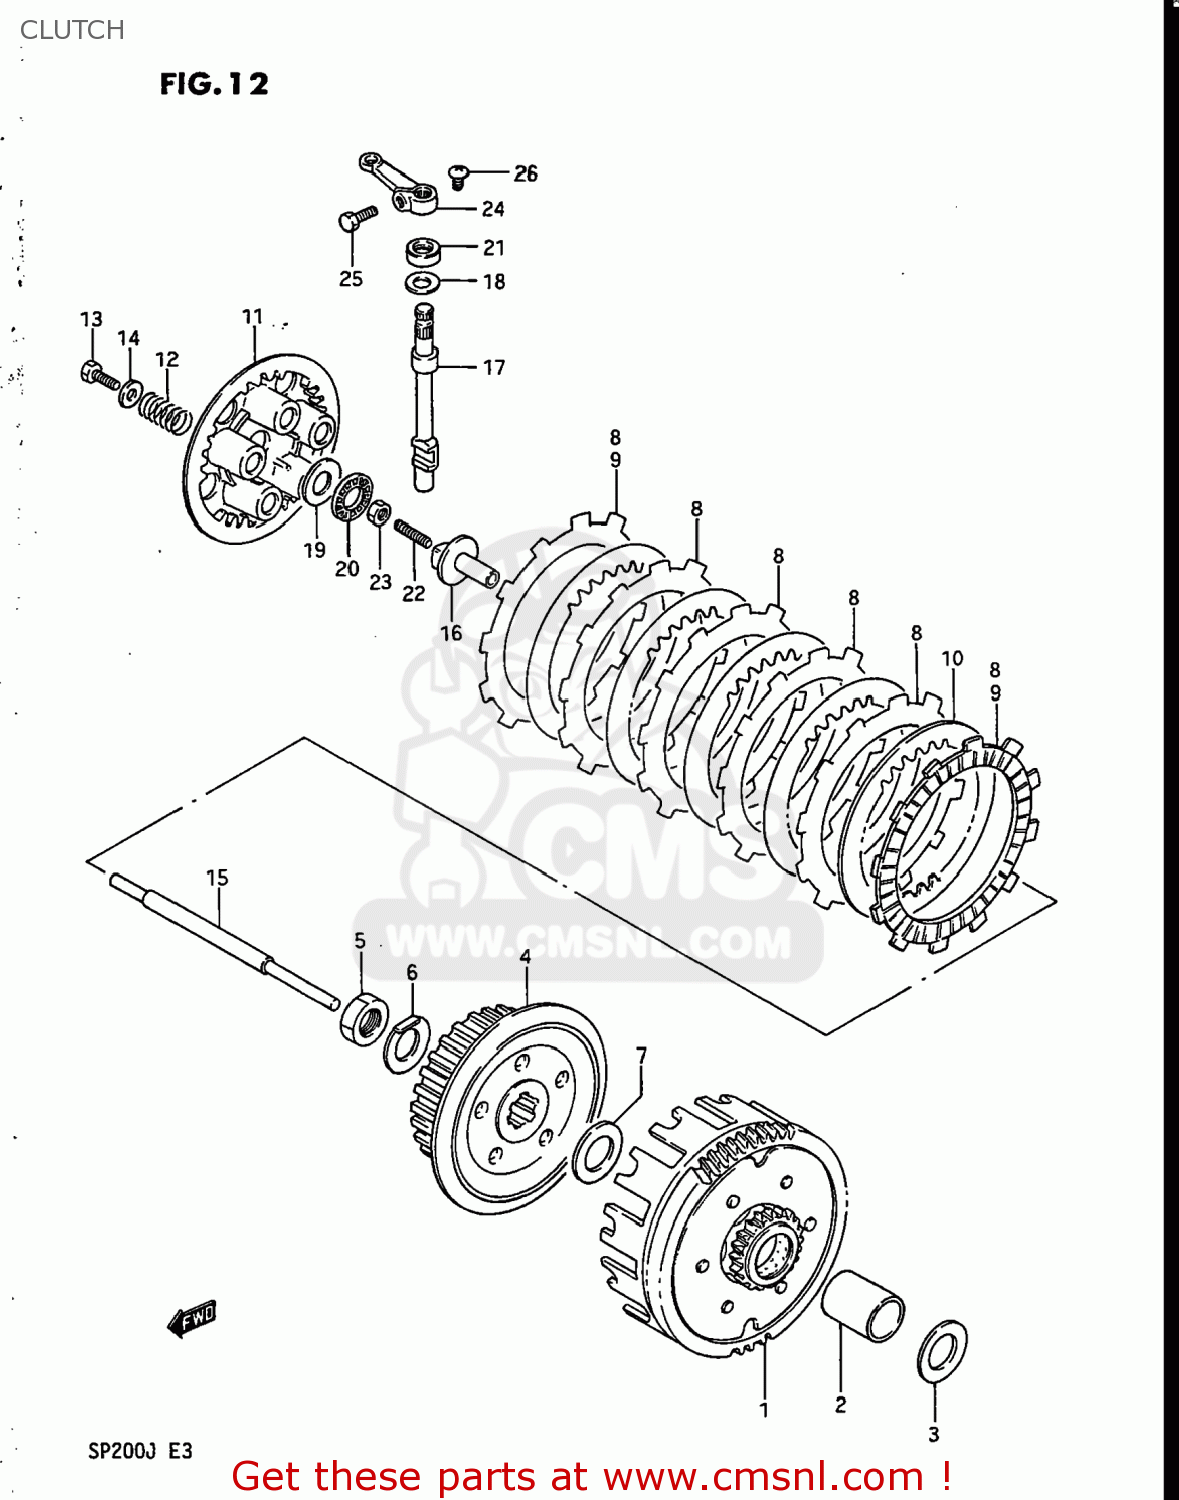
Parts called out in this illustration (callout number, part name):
1	GEAR ASSEMBLY,PRIMARY DRIVE
2	SPACER
3	WASHER
4	HUB,CLUTCH SLEEVE
5	NUT
6	WASHER
7	WASHER
8	PLATE,CLUTCH DRIVE (MCA)
9	PLATE,CLUTCH DRIVE (NAS)
10	PLATE,CLUTCH DRIVEN (NAS)
11	PLATE,CLUTCH PRESSURE
12	SPRING
13	BOLT(5X16)
14	WASHER (5.5X16X1.2)
15	ROD,CLUTCH PUSH
16	PIECE,CLUTCH PUSH
17	CAMSHAFT,CLUTCH RELEASE
18	WASHER,THRUST
19	WASHER
20	BEARING(15X28X2)
21	OIL SEAL
22	SCREW(6X25)
23	NUT 6MM
24	ARM,CLUTCH RELEASE
25	BOLT
26	SCREW
